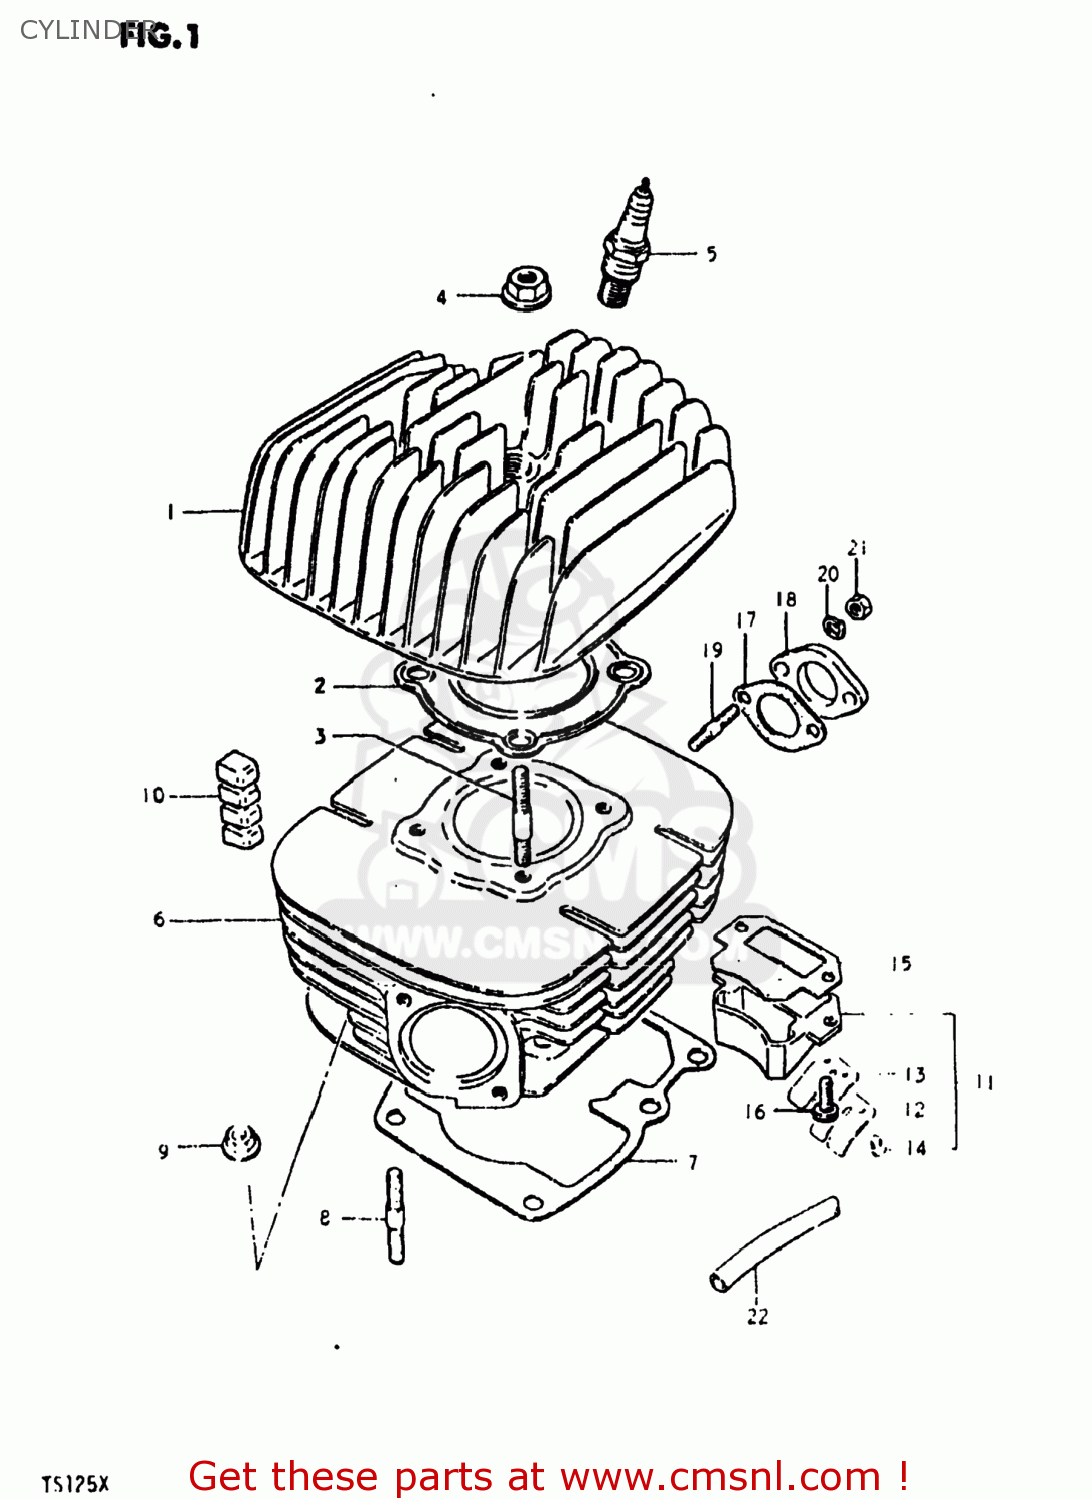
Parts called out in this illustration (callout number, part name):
1	HEAD,CYLINDER
2	GASKET,CYLINDER HEAD (MCA)
3	STUD BOLT
4	NUT
5	SPARK PLUG
6	CYLINDER
7	GASKET,CYLINDER (MCA)
8	STUD 8X25
9	NUT
10	PAD,CYLINDER
11	VALVE ASSEMBLY,REED
12	STOPPER,REED VALVE
13	VALVE,REED
14	SCREW,REED VALVE
15	GASKET,REED VALVE (MCA)
16	SCREW
17	GASKET,CARBURETOR (MCA)
18	INSULATOR,CARBURETOR
19	STUD BOLT
20	LOCK WASHER
21	NUT
22	HOSE
